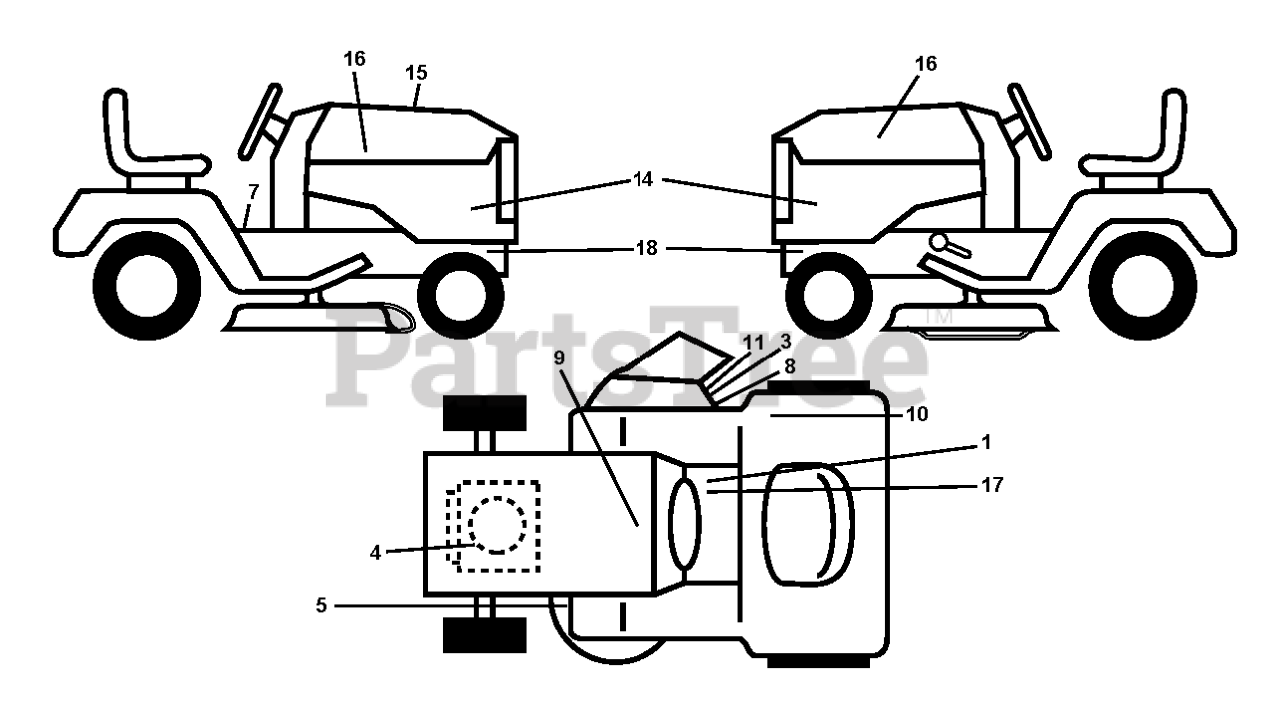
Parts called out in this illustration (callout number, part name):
1	DECAL
3	DECAL, DEFLECT WARNING
4	DECAL
5	DECAL
7	LABEL
8	DECAL.MOWER.SCH.48/54
9	DECAL BTRY SYMBOLS
10	DECAL.FENDER
11	DECAL.INTERNATIONL.CUTFINGER
16	DECAL.HOOD.LOGO.ORANGE.HUSQVAR
17	DECAL PARK BRAKE
